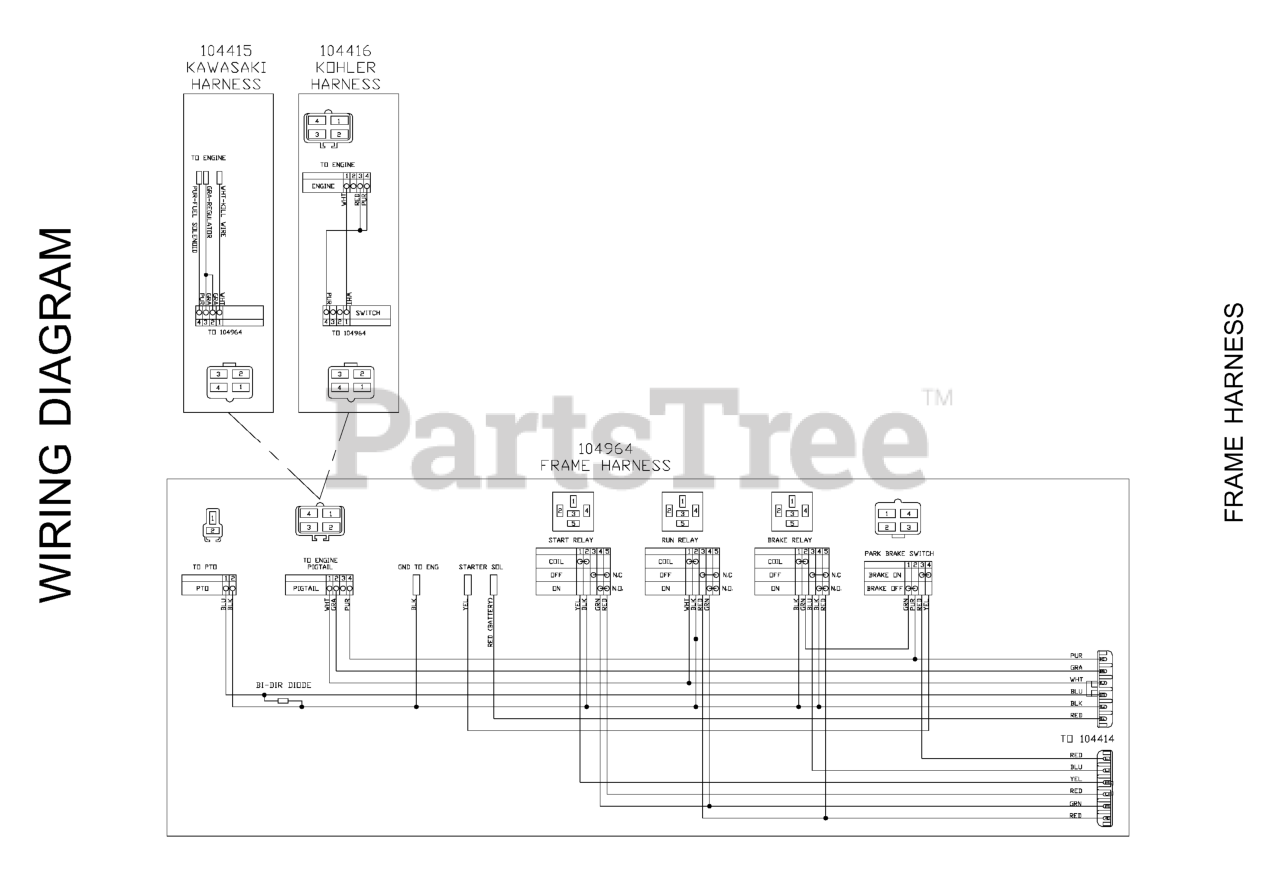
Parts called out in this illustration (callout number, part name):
1	SCREW #10 X 1/2 SELF TAPPING
3	FUSE, 7.5 AMP 32 VOLT ATO
4	FUSE, 20 AMP 32 VOLT ATO
5	SWITCH, INTERLOCK
6	IGNITION SWITCH KIT
7	RP.SWITCH, BLADE
8	DIGITAL HOUR METER
9	SCREW #10-24 X 5/8
10	TAPPED PLATE
11	CONSOLE HARNESS
12	NUT 1/4C CENTERLOCK
13	HCS 1/4C X 5/8
14	POST.CABLE LONG
15	FRAMES HARNESS
16	CABLE POSITIVE, LONG
17	HCS 5/16C X 3/4
19	NUT 5/16C CENTERLOCK
20	CABLE-NEGATIVE
21	BATTERY WET NOT SELLABLE
22	NUT 10-24 NYLOC
23	KEY-PADDED
24	CAP IGNITION NUT
25	DNO IGNITION NUT
26	KOH PIGTAIL
27	KAW PIGTAIL
28	SCREW, #1--24 X 1/2 SLOTTED
30	WASHER 1/4 INT TOOTH
539102757	CABLE POSITIVE
